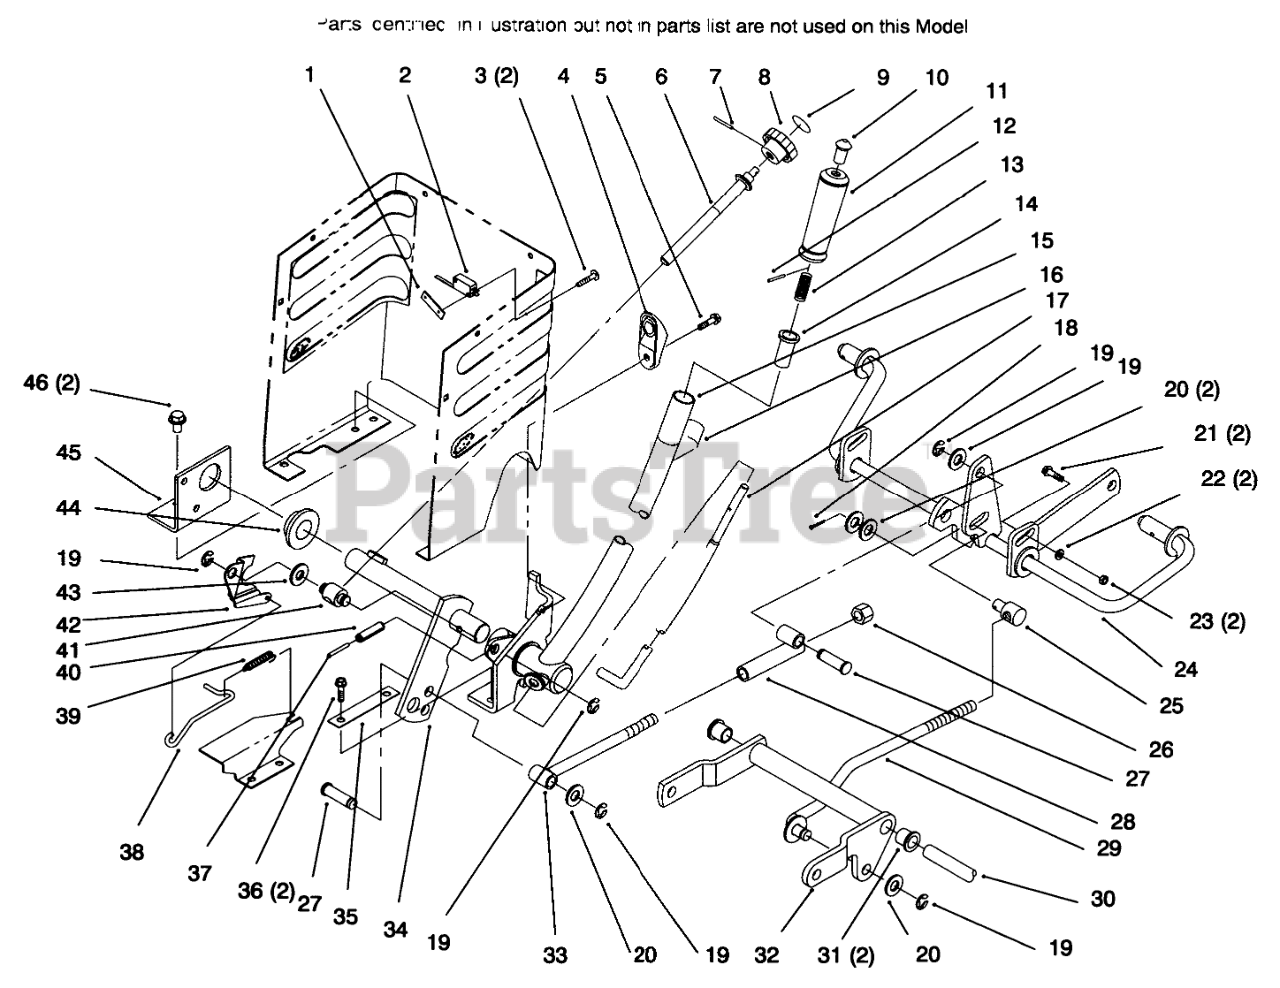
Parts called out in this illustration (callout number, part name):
1	NUT-SPEED
2	SWITCH-MICRO
3	SCREW-HH
4	WEDGE - HOC
5	SCREW-HWH
6	ROD - HOC
7	PIN-SPIROL
9	DECAL-HEIGHT KNOB
10	TIP-ROD
11	GRIP-HANDLE
12	PIN-SPIROL
13	SPRING-COMPRESSION
14	RETAINER-SPRING
15	LEVER-LIFT
16	Decal-Lift (Only On: 78085)
16	Decal-Lift (Only On: 72104)
17	ROD-LEVER, LIFT
18	PIN-COTTER
19	RING-RETAINING, EXTERNAL
20	WASHER-FLAT
21	BOLT-CARR
22	WASHER-FLAT
23	NUT-LOCK, NI
24	SHAFT-GAGE
25	ROD-TRUNNION LIFT
26	NUT-LOCK, NI
30	SHAFT-PIVOT, PEDAL
31	BUSHING-FLANGE
32	ARM-PIVOT
34	SHAFT-LIFT
36	Screw-HH
37	PIN-SPRING
38	ROD - HOC INDICATOR
39	SPRING - EXTENSION
40	PIN-ROLL
41	TRUNNION
42	PLATE - HOC GAGE
43	BEARING-FLANGE
44	BRACKET-PIVOT, LINKAGE
45	SCREW-HWHTF
